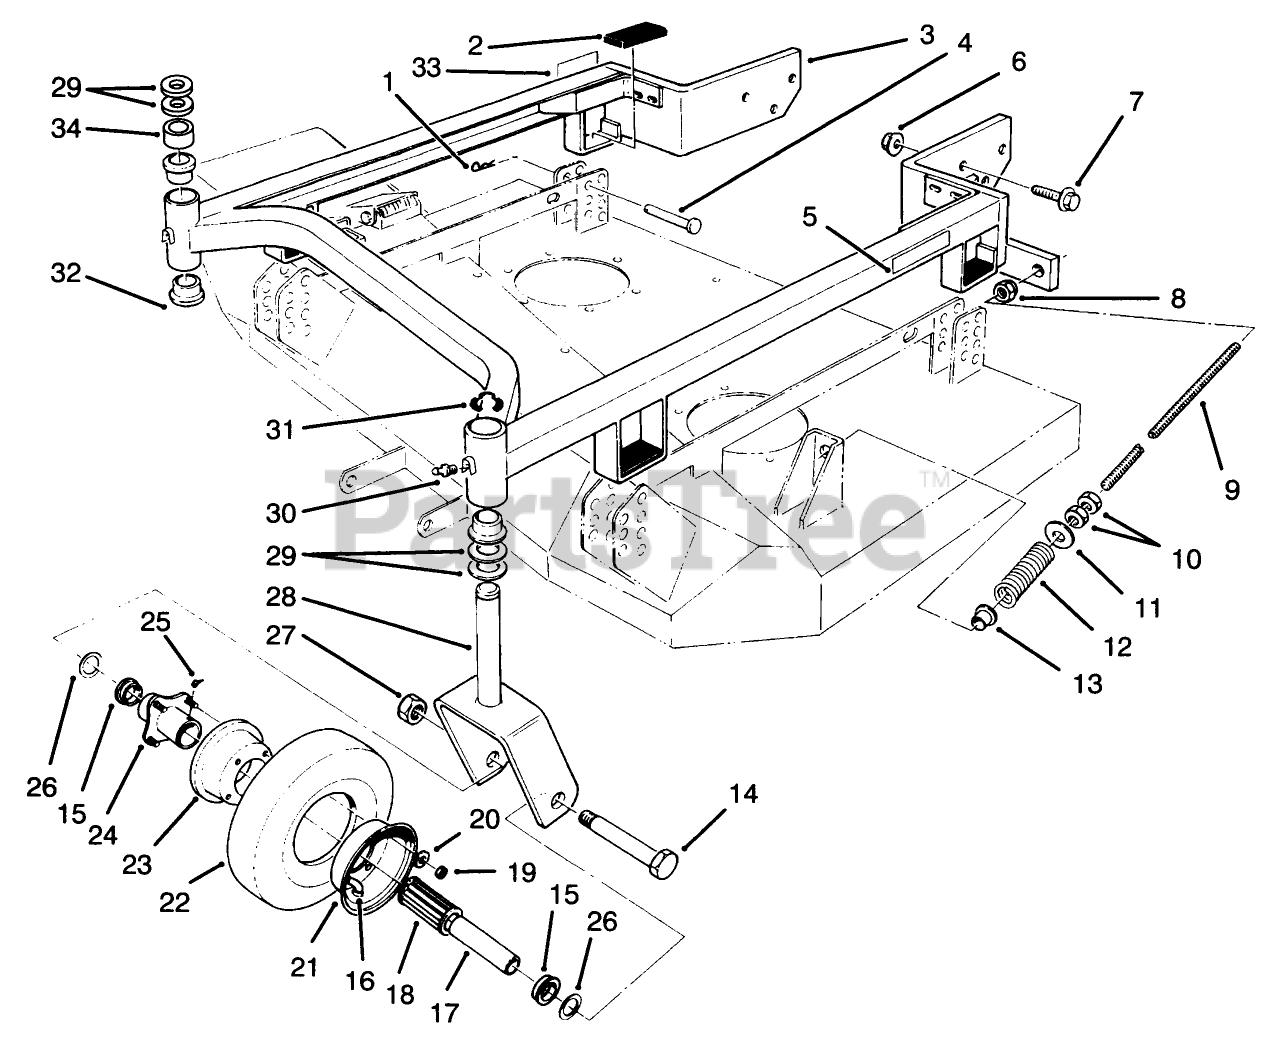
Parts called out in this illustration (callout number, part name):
1	PIN-HAIR
2	CUSHION-RUBBER
3	Frame-Carrier (Incl. Ref. #32)
4	PIN-CLEVIS
5	DECAL-HOC, LH
6	NUT-HF
7	SCREW-HHF
8	NUT-LOCK, NI
9	SHAFT-ADJUSTING
10	NUT-JAM
11	WASHER
12	SPRING
13	BUSHING-FLANGE
14	SCREW-HH
15	BEARING-OUTSIDE
16	TUBE-INNER (W/VALVE)
17	SPANNER-TIRE
18	BEARING-ROLLER
19	NUT-HEX
20	WASHER-LOCK
21	MALE WHEEL HALF
23	FEMALE WHEEL HALF
24	HUB-CENTER
25	FITTING-GREASE
26	WASHER-FLAT
27	NUT-HEX
28	Fork
29	WASHER-THRUST
30	FITTING-GREASE
31	RING-RETAINING
32	BUSHING
33	DECAL-HOC, RH
34	SPACER-CASTOR
